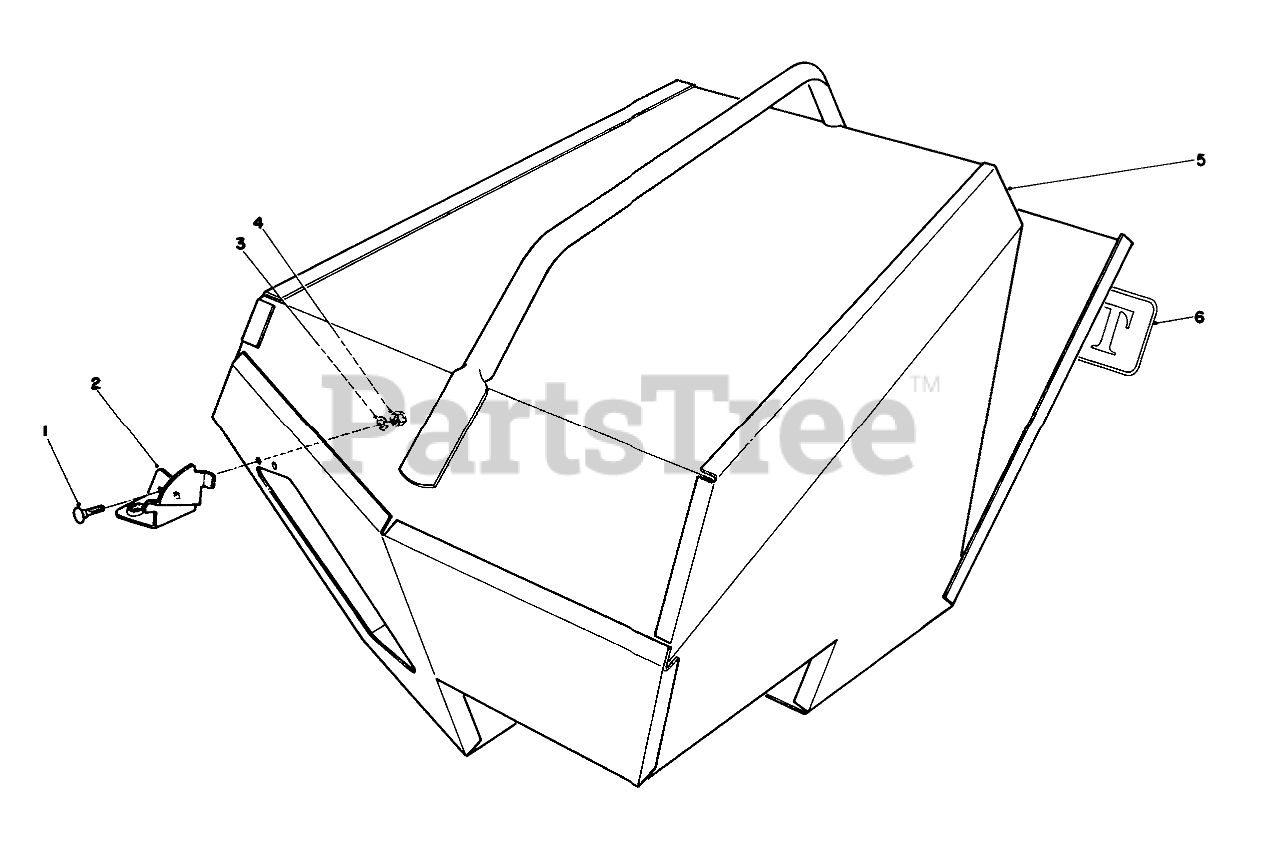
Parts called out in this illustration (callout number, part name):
1	SCREW-CARR
2	Bracket-Latch
3	WASHER-FLAT
4	NUT-LOCK, NI
5	Bag-Steel
6	Decal
